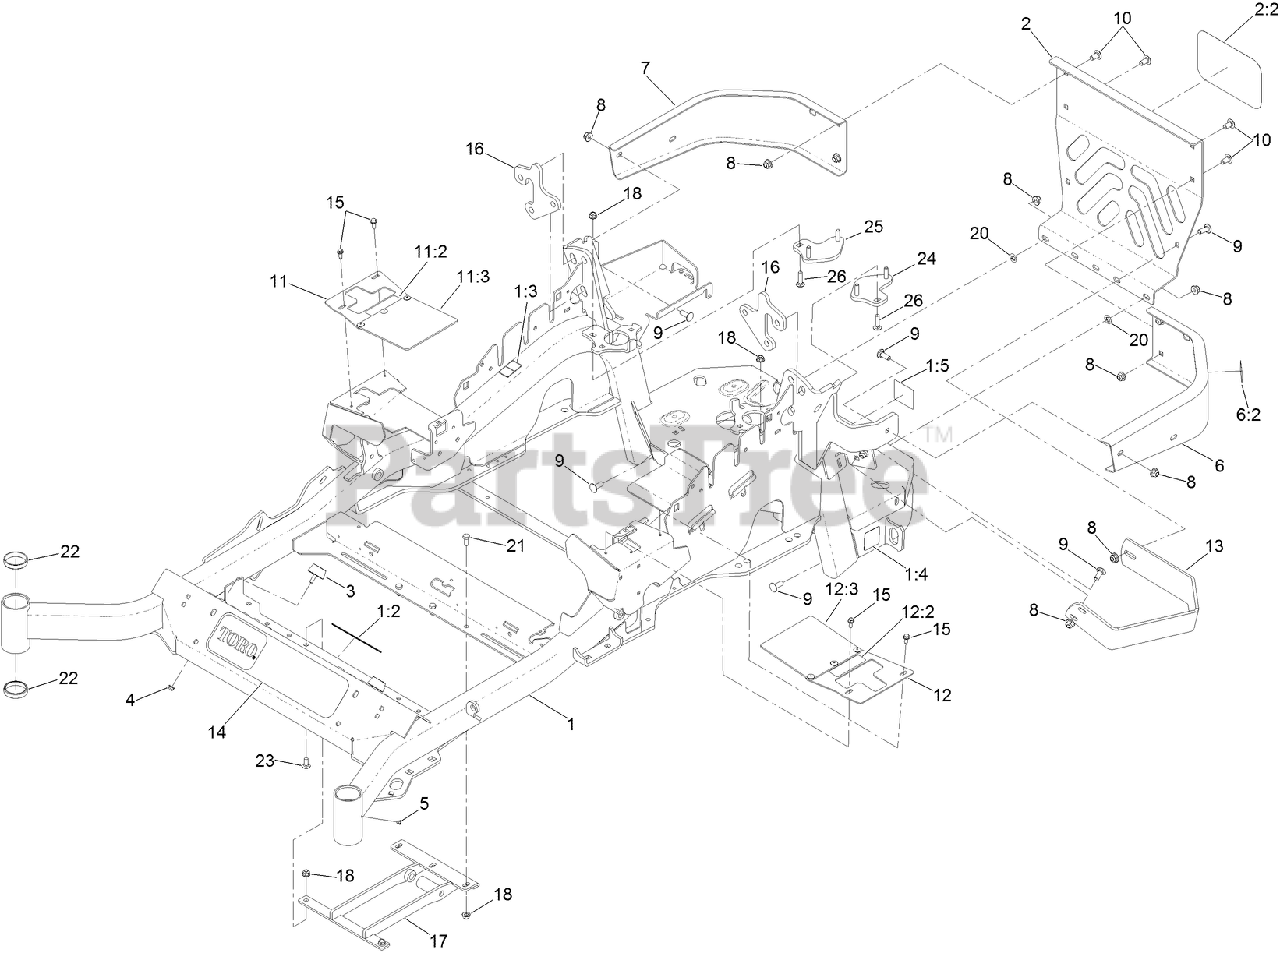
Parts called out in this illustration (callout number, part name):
1	MAINFRAME ASM
1:2	DECAL-DANGER
1:3	DECAL-WARNING
1:4	DECAL-HAZARD, PINCHED FINGER
1:5	DECAL-ARRESTOR, SPARK
2	REAR GUARD ASM
2:2	DECAL
3	BUMPER
4	NUT-HF
6	LH BUMPER ASM
6:2	DECAL-WARNING
7	BUMPER-RH
8	NUT-HF, NI
9	SCREW-CARR
10	SCREW-CARR
11	RH MOTION CONTROL COVER ASM
11:2	DECAL-CONTROL, MOTION
11:3	FLAP-RUBBER
12	LH MOTION CONTROL COVER ASM
12:2	DECAL-CONTROL, MOTION
12:3	FLAP-RUBBER
13	GUARD-MUFFLER
15	SCREW-HWH
16	PLATE-MOUNT, SHOCK
17	MOUNT-LOWER
18	NUT-HF, NI
20	NUT-PUSH
21	SCREW-HH
22	CUP-BEARING
23	SCREW-CARR
24	LH PLATE ASM (W/STUDS)
25	RH PLATE ASM (W/STUDS)
26	SCREW-CARR
